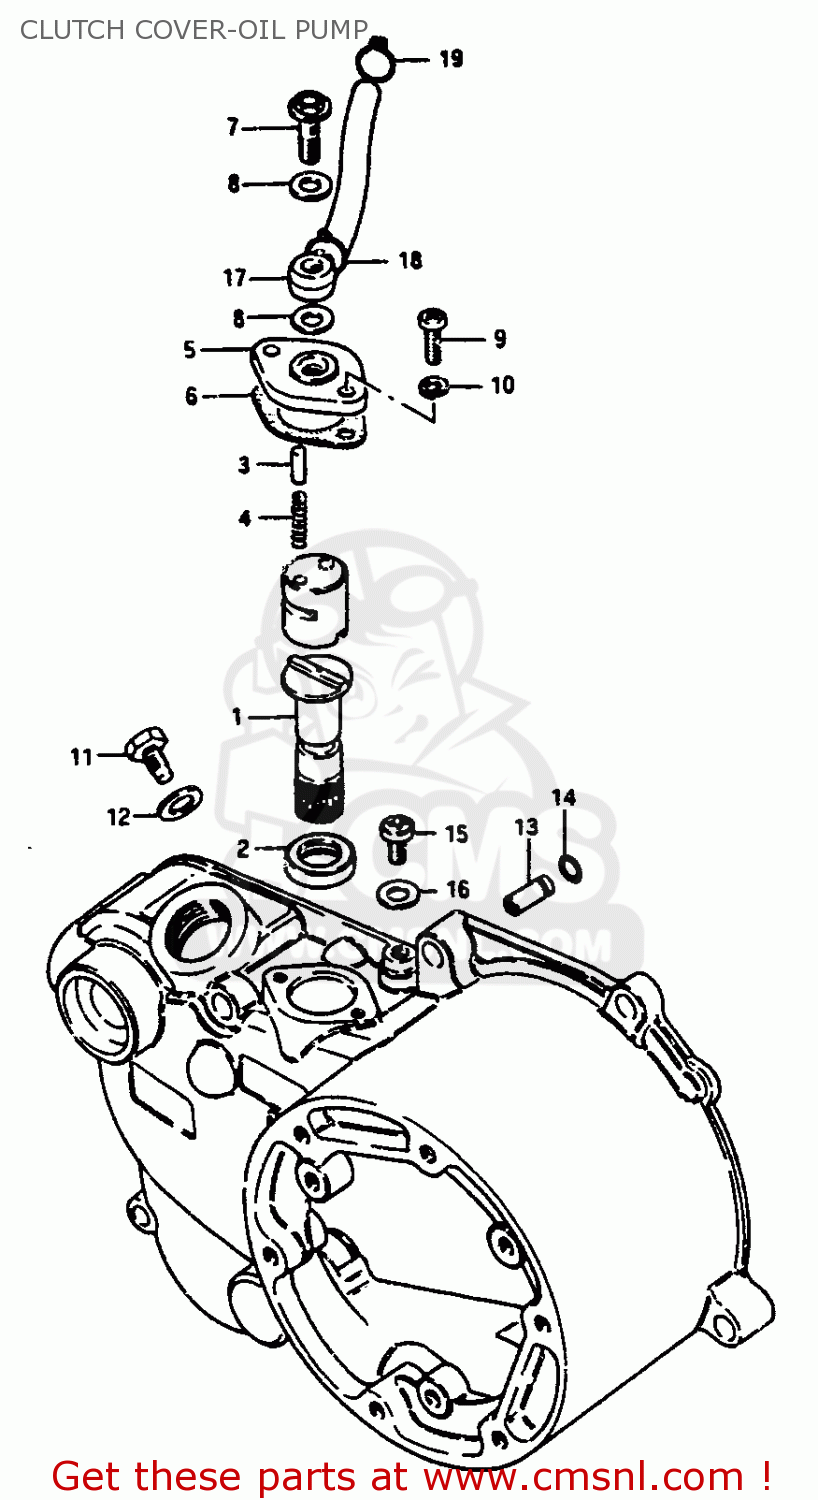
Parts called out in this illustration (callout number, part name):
1	GEAR,OIL PUMP DRIVE
2	SEAL,OIL(12X18.5X3)
3	PIN(2.3X7.5)
4	SPRING
5	CAM,OIL PUMP
6	GASKET,OIL PUMP (MCA)
7	SCREW
8	GASKET(6.2X11X1).2 (NAS)
10	WASHER,LOCK 4M
11	BOLT(6X10)
12	WASHER
13	VALVE,CRANK CHECK
14	O RING(D:1.05,ID:3.1)
15	SCREW
16	GASKET(5X9.5X1) (NAS)
17	HOSE,OIL NO.1
18	CLIP
19	CLIP
